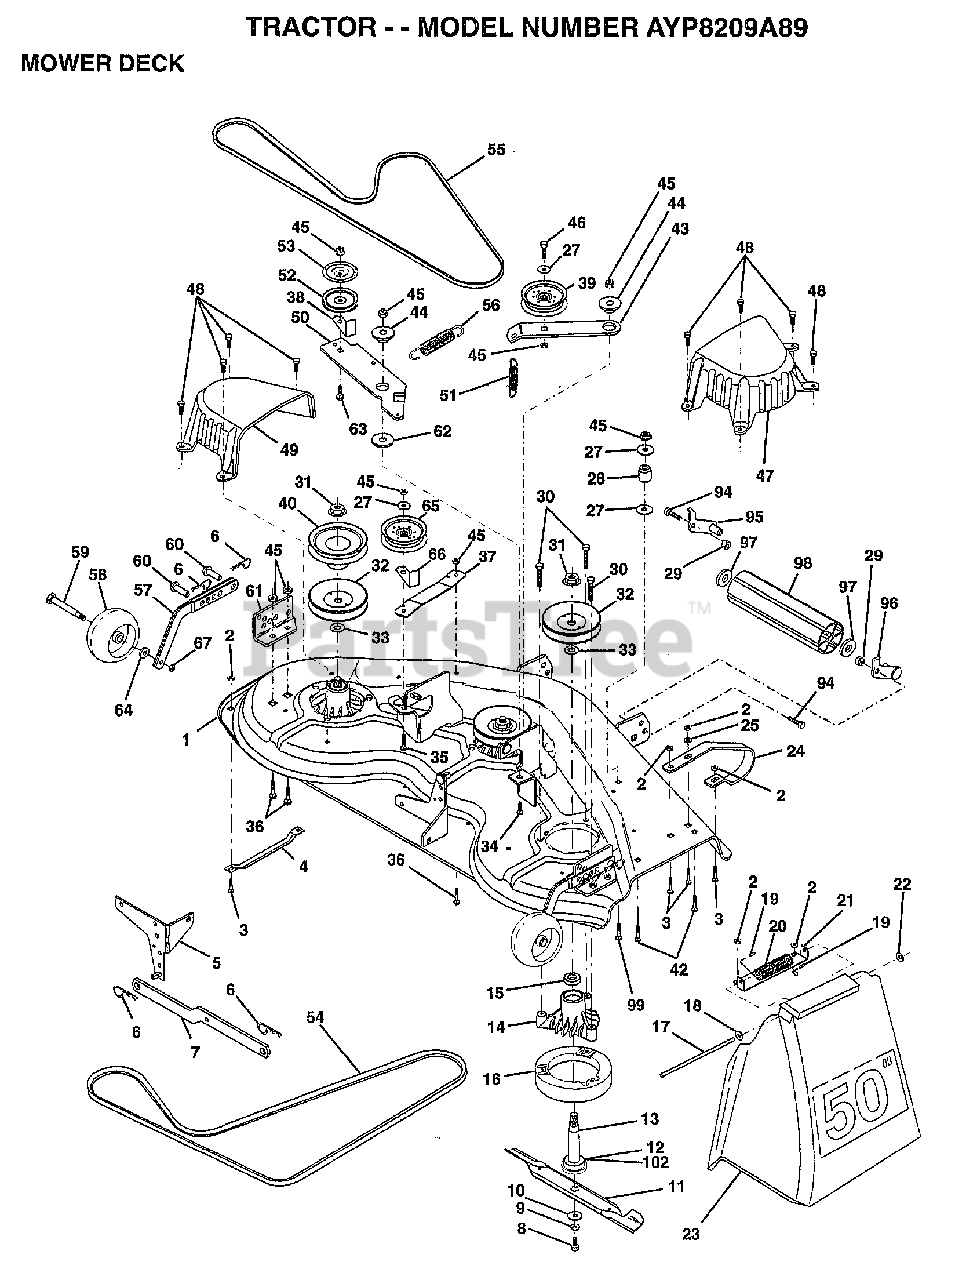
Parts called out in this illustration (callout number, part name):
1	"DECK ASM-50"""
4	RUNNER-LH M
5	BRKT.ASM.SW.44/50
8	BLADE BOLT
10	WASHER.HARD.BLADE
11	"BLADE.50"" HD"
12	BEARING.BALL
13	SHAFT.ASM.W/BRNG
14	HOUSING.MAND.44.V
15	BEARING
16	STRIPPER RND MWR
17	ROD-HINGE T
18	WASHER
19	CAP-SLEEVE LT
20	SPRING TORSION
21	BRKT DEFLECTOR
22	NUT PUSH M
23	DEFLECTOR
24	"RUNNER RH 50"" DK"
25	WASHER M
27	WASHER
29	NUT
30	"SCREW-THD ROLL,WA"
32	PULLEY.MANDREL.42
33	WASHER
34	BOLT.3/8-14X1.25
35	BOLT
36	BOLT D
37	STIFFENER.ARM.IDL
38	"KEEPER-BELT,IDLER"
39	FLAT IDLER PULLEY
40	"PULLEY.DRIVEN.44"""
42	BOLT
43	"ARM.IDLER.SEC.44"""
44	SPACER RETAINER
47	"COVER.MAND.RH.44"""
48	SCREW.1/4-20X5/8
49	COVER.MANDREL.LH
50	ARM.IDLER.PRIMARY
51	"SPRING.SEC.44""VEN"
52	PULLEY.IDLER.VGRO
53	SHIELD.IDLER.44.V
54	BELT V PRIM 50
55	BELT-V.SEC.46.KEL
56	SPRING.EXT.DECK.
57	BAR.ASM.GUAGE.WHL
58	WHEEL GAGE DONUT
59	BOLT.SHOULDER
60	PIN.CLEVIS
61	BRACKET.GUAGE.WHL
62	HARDENED WASHER
63	BOLT.3/8-16X1.50
64	WASHER
65	PULLEY IDELR FLAT
66	"KEEPER-BELT,IDLER"
67	LOCKNUT
94	BOLT
97	WASHER
99	BOLT
102	WASHER.FELT.
